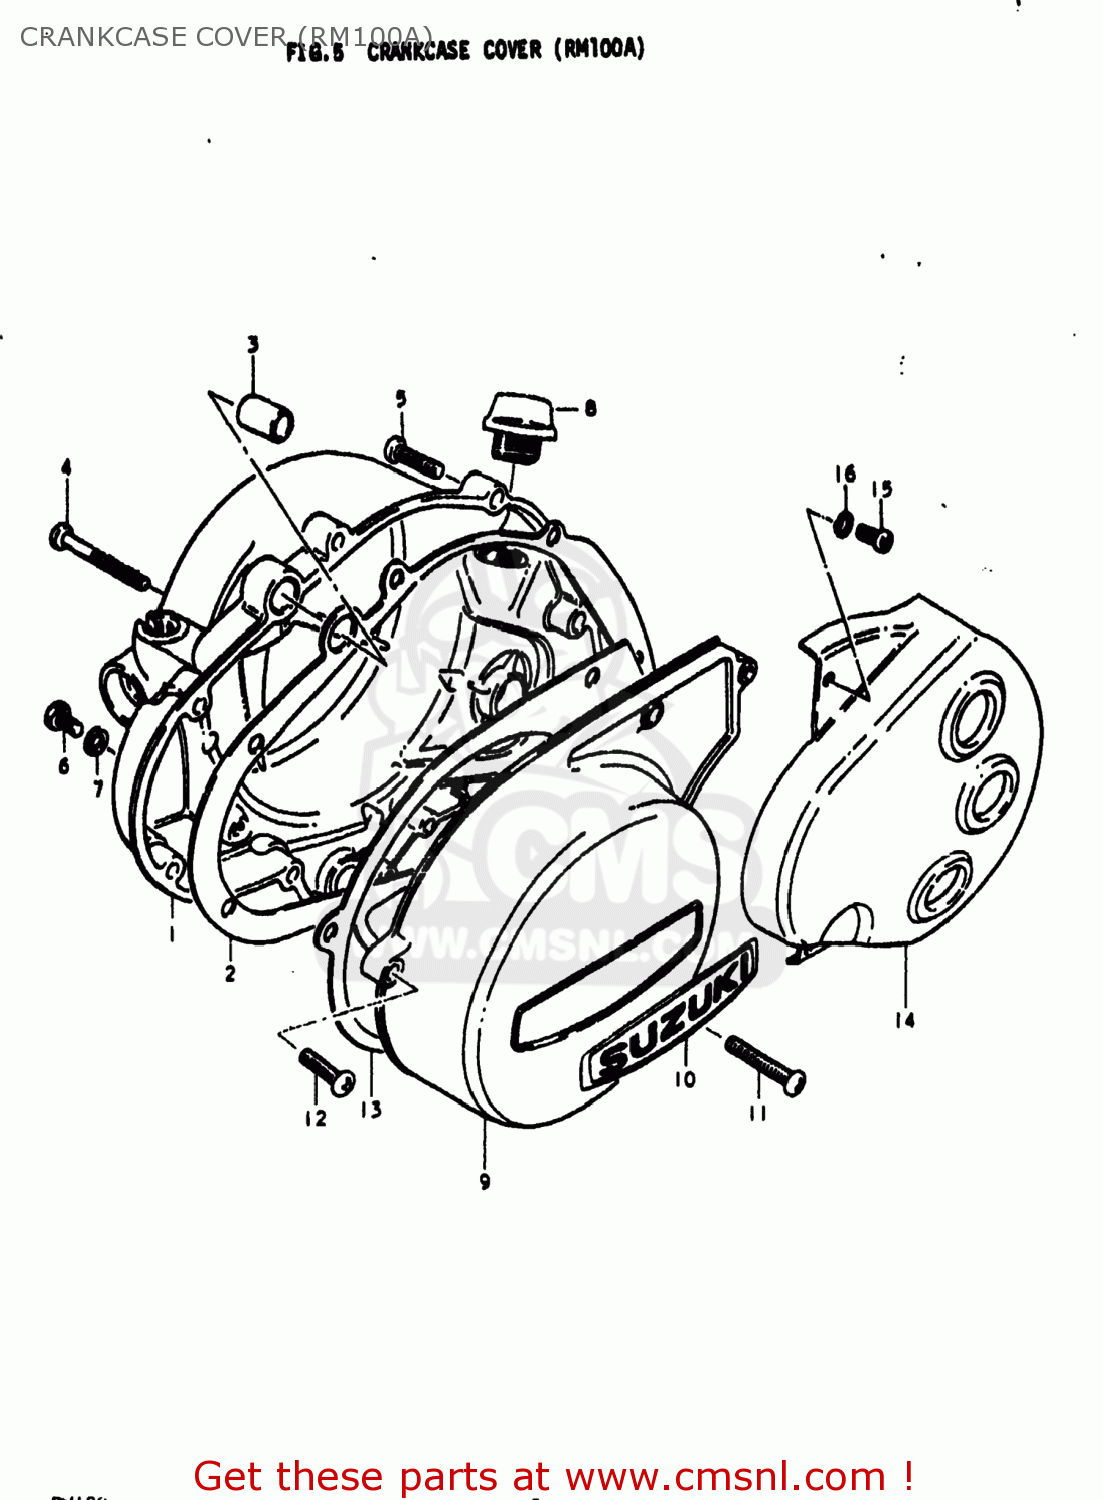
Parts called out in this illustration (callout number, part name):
1	CLUTCH COVER
2	GASKET,CLUTCH COVER (MCA)
3	PIN
4	SCREW (6X45)
5	SCREW
6	SCREW(6X10)
7	GASKET(6.2X11X1) (NAS)
8	PLUG,OIL FILTER
9	COVER
10	EMBLEM,MAGNETO COVER
11	SCREW
12	SCREW
13	GASKET,CLUTCH COVER (NAS)
14	COVER,ENGINE SPROCKET GLOSS
15	SCREW
16	LOCK WASHER
